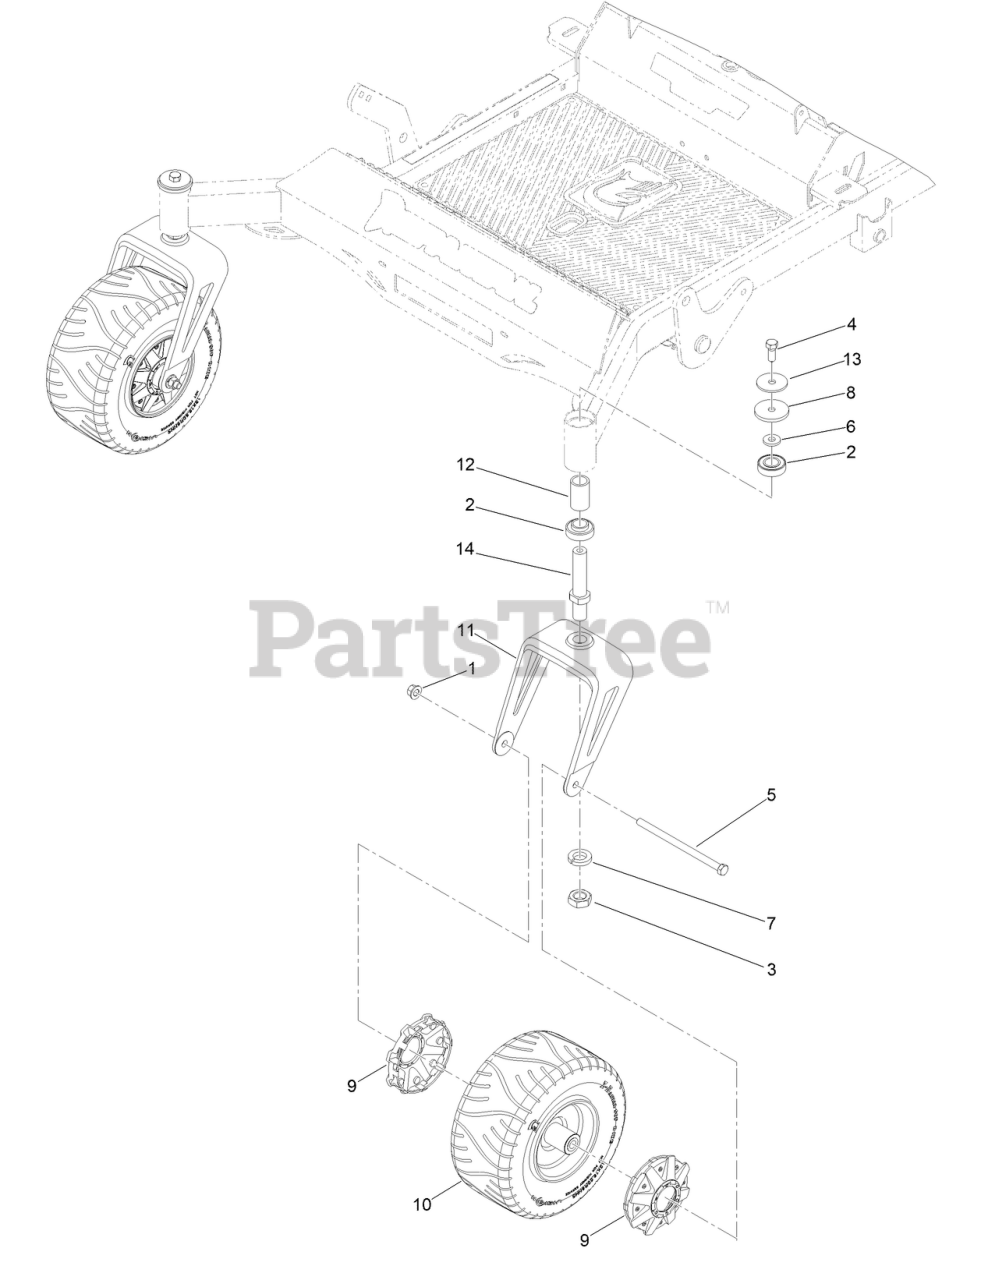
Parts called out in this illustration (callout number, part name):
1	NUT-LOCK
2	BEARING-BALL
4	1/2-20 X 1-1/4 HEX FLANGE BOLT GR 8 YZ
5	SCREW-HH
6	1/2 FENDER WASHER 1-1/4IN OD ZINC
7	1IN L/W MED SPLIT ZC
8	FT HUB PLASTIC WASHER
9	MWR FT WHEEL HUB CAP
10	SPARTAN RADIAL FT TIRE AND WHEEL ASSM
11	RT AND SRT CASTER WHEEL FORK
12	CASTER FORK SHAFT BEARING SPACER
13	MWR CASTER SHAFT WASHER
14	MWR CASTER SHAFT
